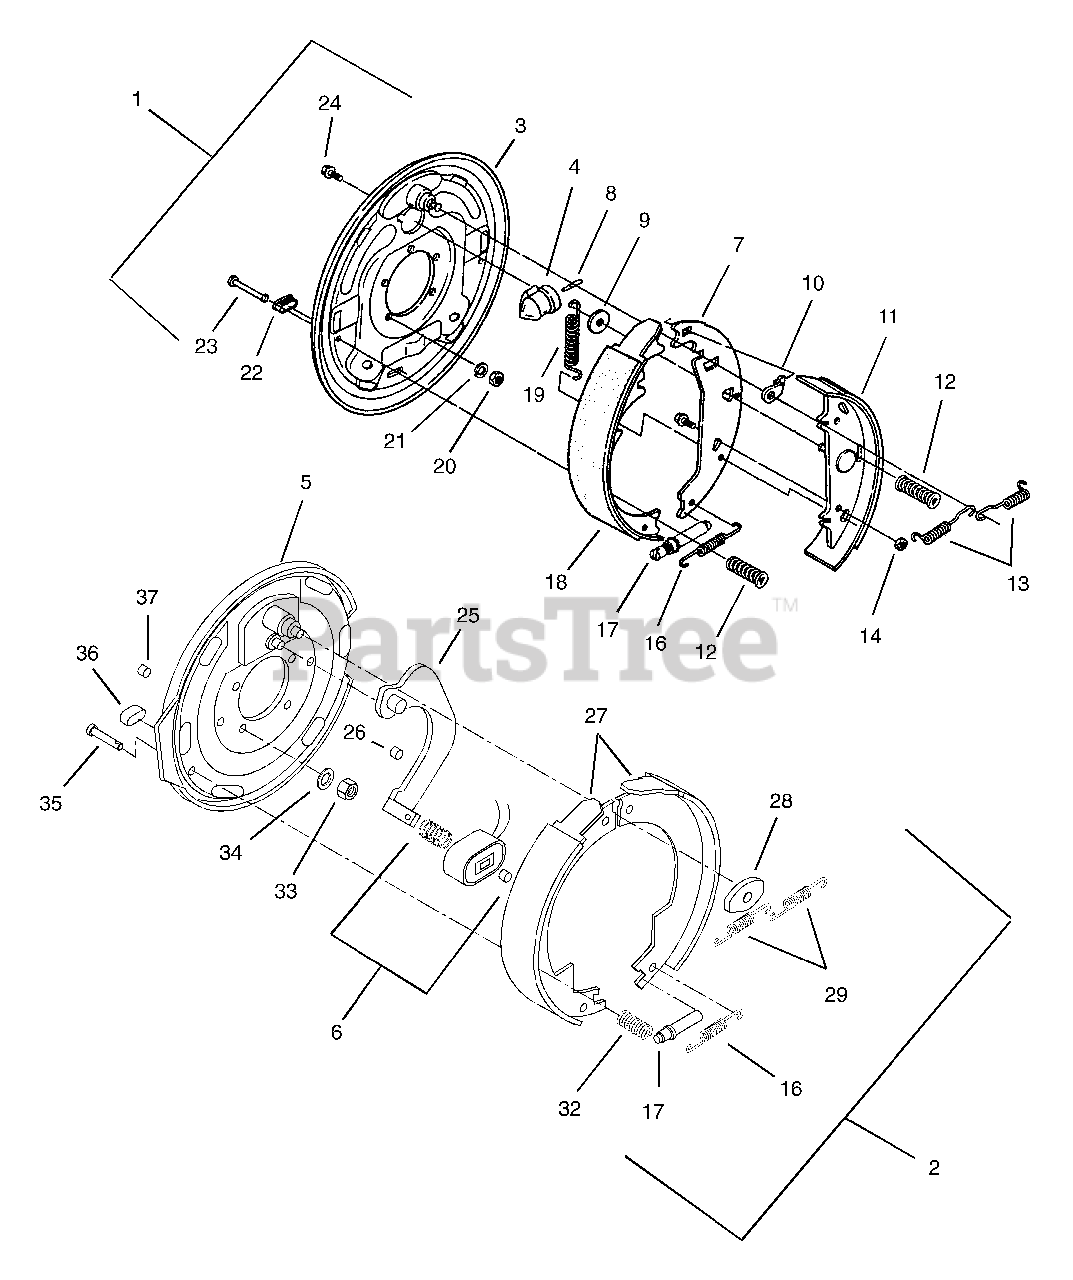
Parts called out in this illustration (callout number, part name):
1	Left Hand Brake Assembly-Hydraulic
1	Right Hand Brake Assembly-Hyd
2	Left Hand Brake Assembly Electric
2	Right Hand Brake Assembly-Electric
3	Backing Plate Assembly-Hyd
4	Left Hand Brake Cylinder-Hyd
4	Right Hand Brake Cylinder Kit-Hyd
5	Backing Plate Assembly-Electric
6	Magnet Kit
7	Shoe Lever-Hydraulic
